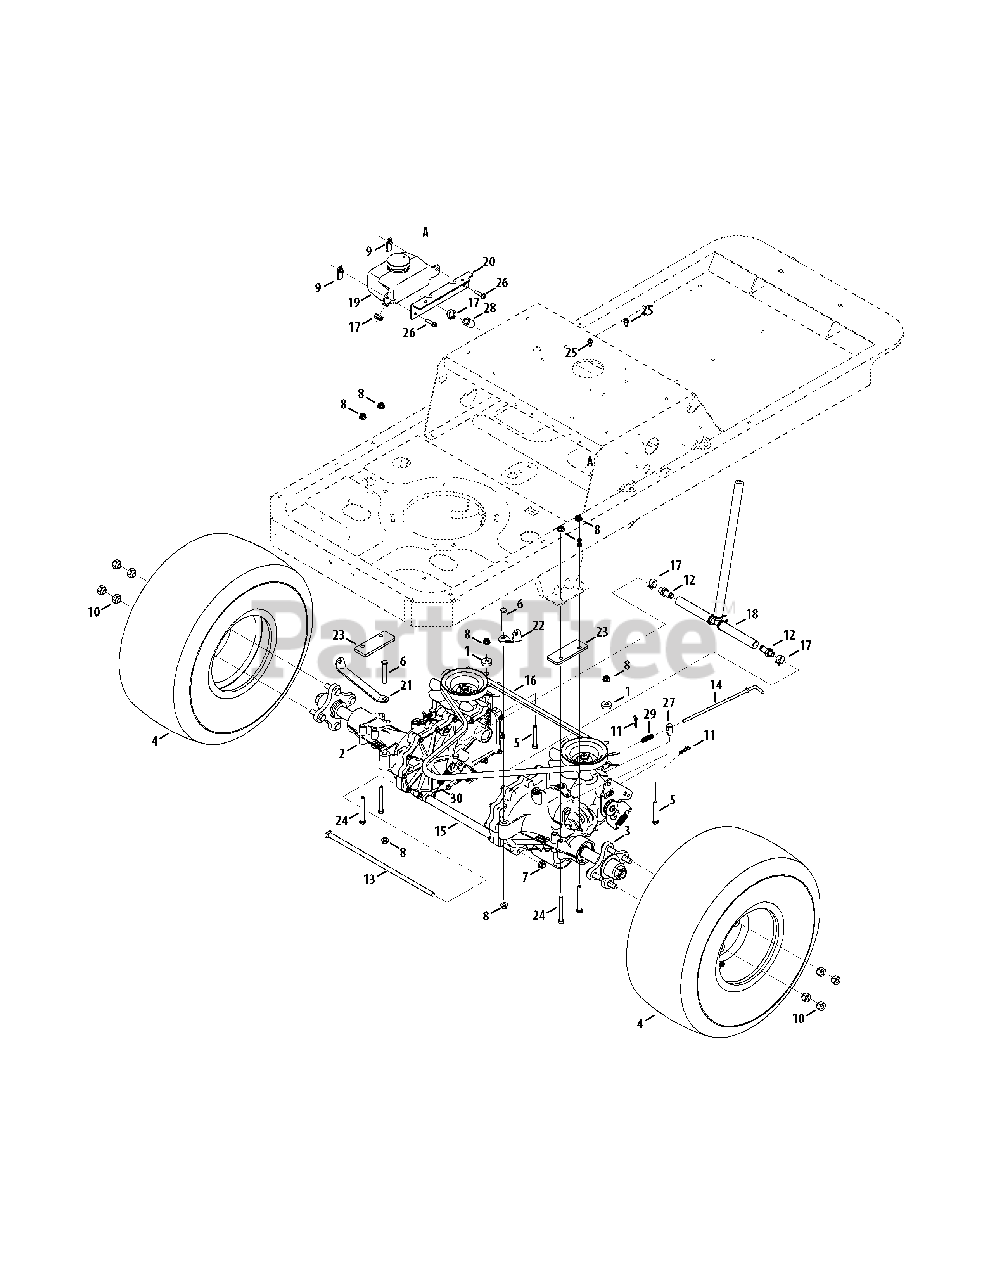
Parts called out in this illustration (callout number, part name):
1	Flat Washer, .35ID x 1.0 OD x .25
2	Transmission Assembly, LH
3	Transmission Assembly, RH
4	Wheel Assembly, 20 x 10 x 8
5	Hex Cap Screw, 5/16-18 x 2.75
6	Hex Cap Screw, 5/16-18 x 2.25
7	Flange Lock Nut, 3/8-16
8	Hex Flange Nut, 5/16-18
9	Nut, 1/4-20
10	Lug Nut, 7/16-14
11	Bow-Tie Cotter Pin
12	Steering Fitting
13	Rod, .377 Dia. x 14.75 Lg.
14	Bypass Rod
15	Tube, 7/16 x 3/4 x 11.3
16	V-Belt
17	Hose Clamp
18	Breather Assembly
19	Expansion Tank Assembly
20	Expansion Tank Bracket Mount
21	Transmission Brace - LH
22	Transmission Brace - RH
23	Transmission Spacer
24	Screw, 5/16-18 x 3.00
25	TT Screw, 1/4-20 x .500
26	TT Screw, 1/4-20 x 1.00
27	Ferrule, .325ID x .312OD
29	Compression Spring, .405 x 1.17
30	Extension Spring, .545OD x 4.55 Lg.
